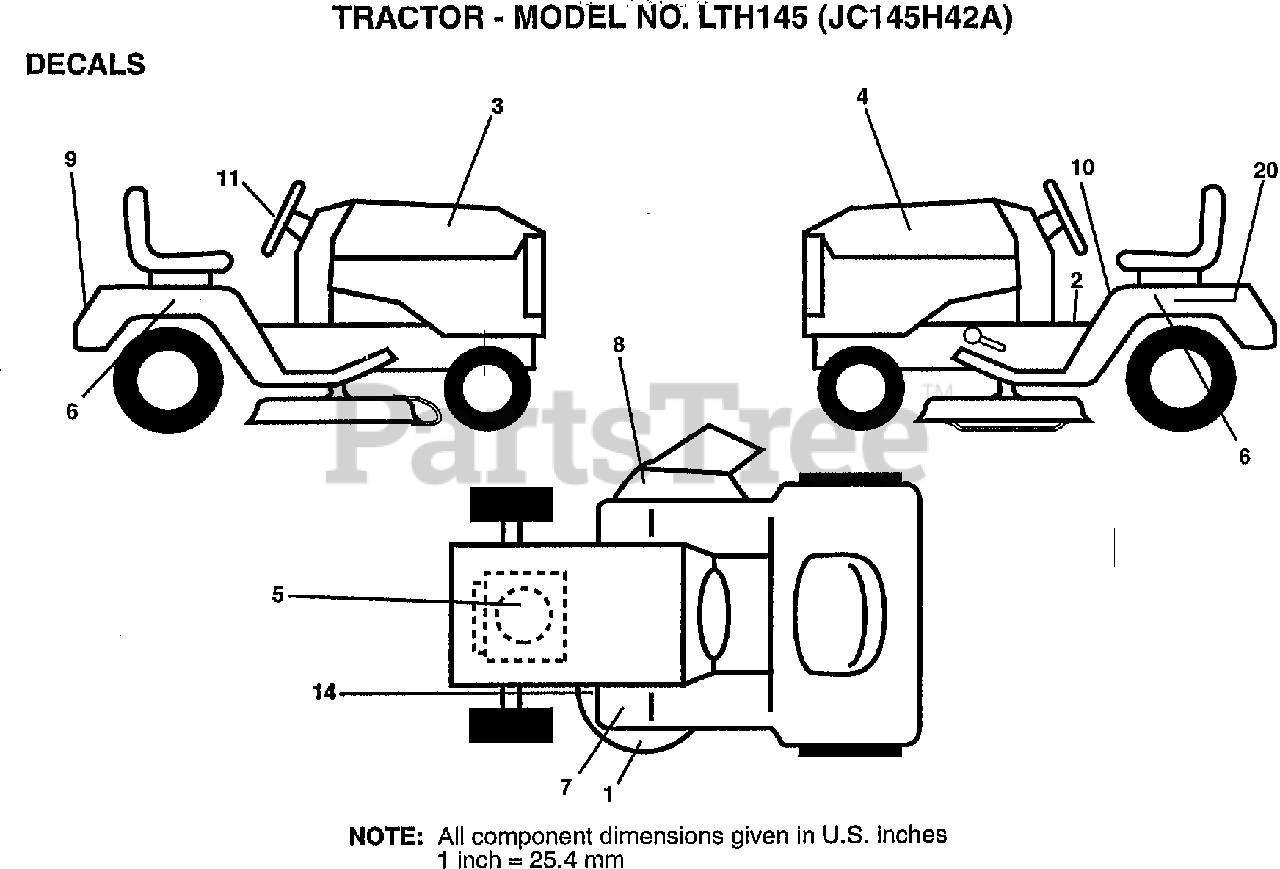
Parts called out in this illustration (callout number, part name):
1	DECAL MOWER ENVIRO WHITE
3	DECAL HOOD RH
4	"DECAL HOOD,LH,LTH"
6	DECAL.FEND.AUTO.
9	DECAL.FEND.LR/LT
11	DECAL INS STRG
